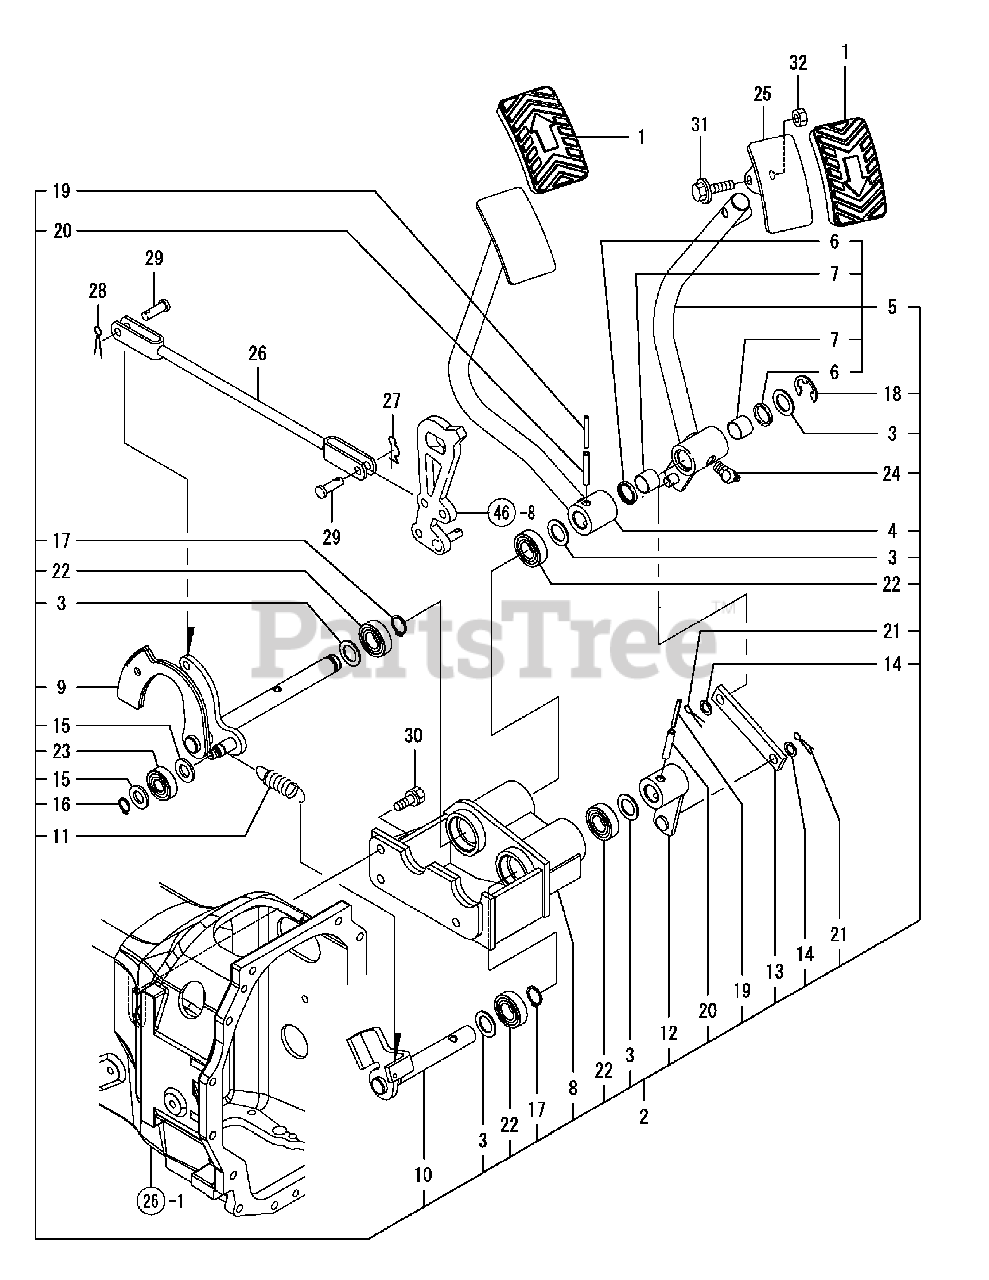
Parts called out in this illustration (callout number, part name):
2	Pedal Kit, Hst
3	Linner 17.5X27X1.6
4	Pedal Assy, Forward
5	Pedal Assy, Reverse
8	Bracket, Hst Pedal
9	Shaft Assy, Pedal
11	Spring,Reverse Pedal
12	Arm Assy, Shaft
14	Spacer 10X15X1
15	Washer 12, Polished
19	Spring Pin 3.5X36
20	Spring Pin 6X36
21	Cotter Pin 1.6X16
23	Ball Bearing 6201Uu
24	Nipple B, Grease
25	Head Assy, Pedal
26	Rod, Hydraulic
27	Pin 8, Come-Off Snap
28	Cotter Pin 2.0X20
31	Bolt M 8X 35 Plated
